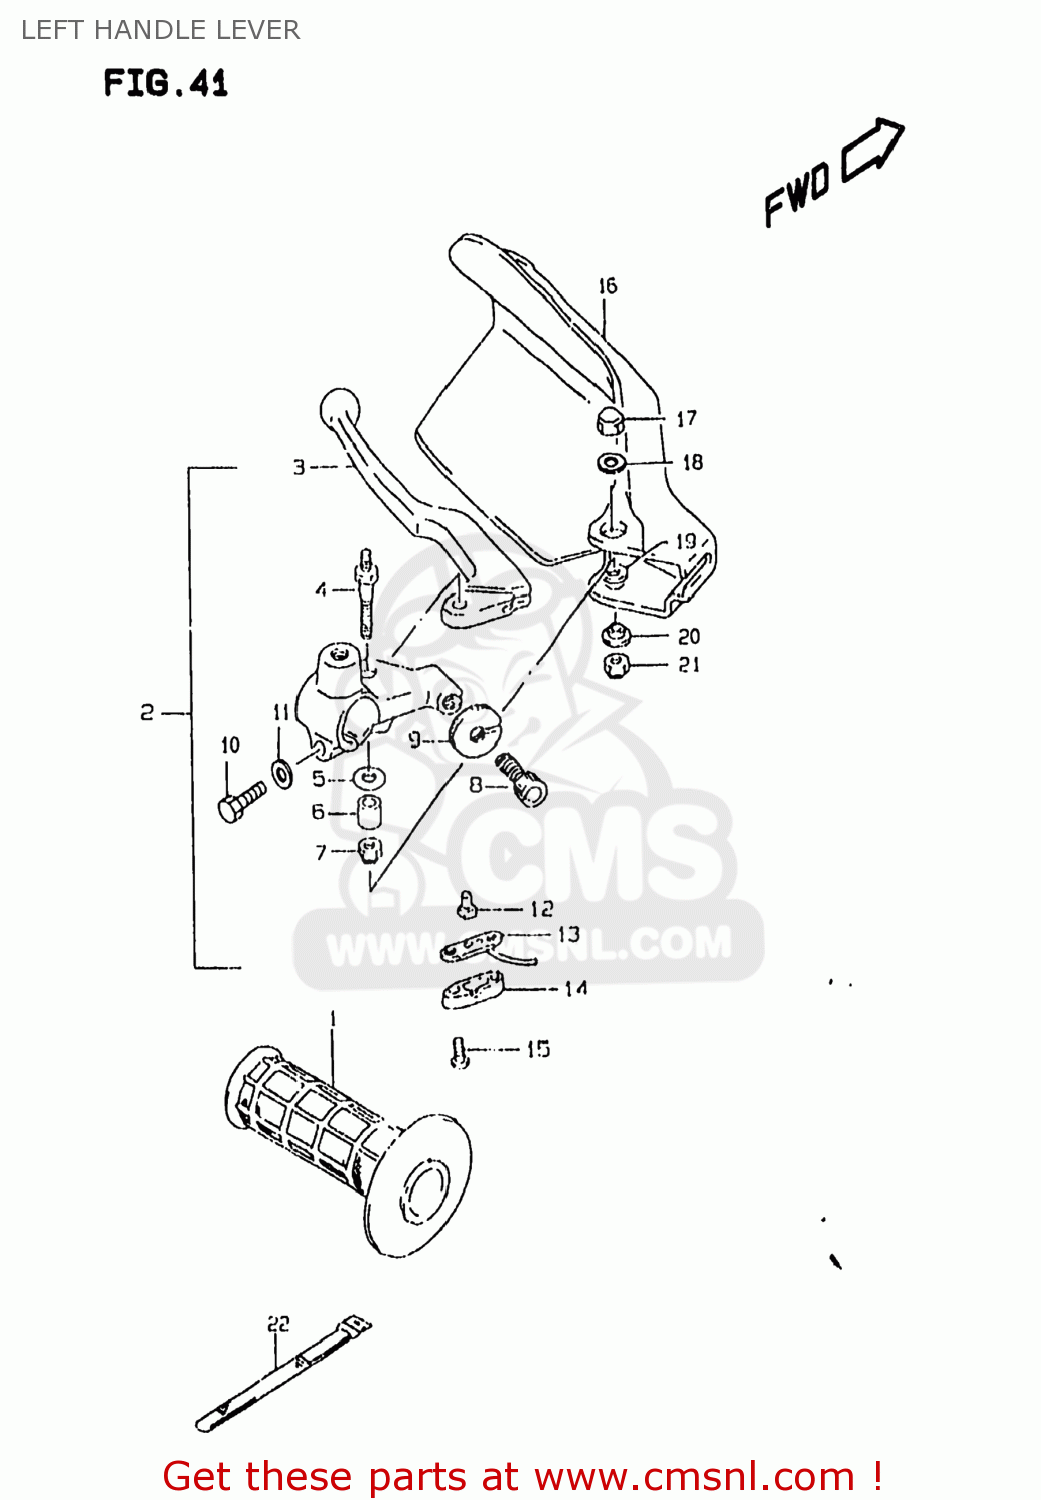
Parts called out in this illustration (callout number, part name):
1	GRIP,L
2	LEVER ASSY,CLUTCH
3	LEVER,CLUTCH
4	BOLT,LEVER SET
5	WASHER
6	SPACER,LEVER SET
7	NUT
8	ADJUSTER,CABLE
9	NUT,LOCK
10	BOLT
11	WASHER
12	CONTACT,SWITCH
13	HARNESS ASSY,WIRE
14	COVER,FR BK TERMINAL BASE
15	SCREW
16	COVER,KNUCKLE,LEFT
17	NUT
18	WASHER(6.5X20X1.6)
19	WASHER(6.5X16X1.2)
20	WASHER
21	NUT 6MM
22	CLAMP(L:120)
